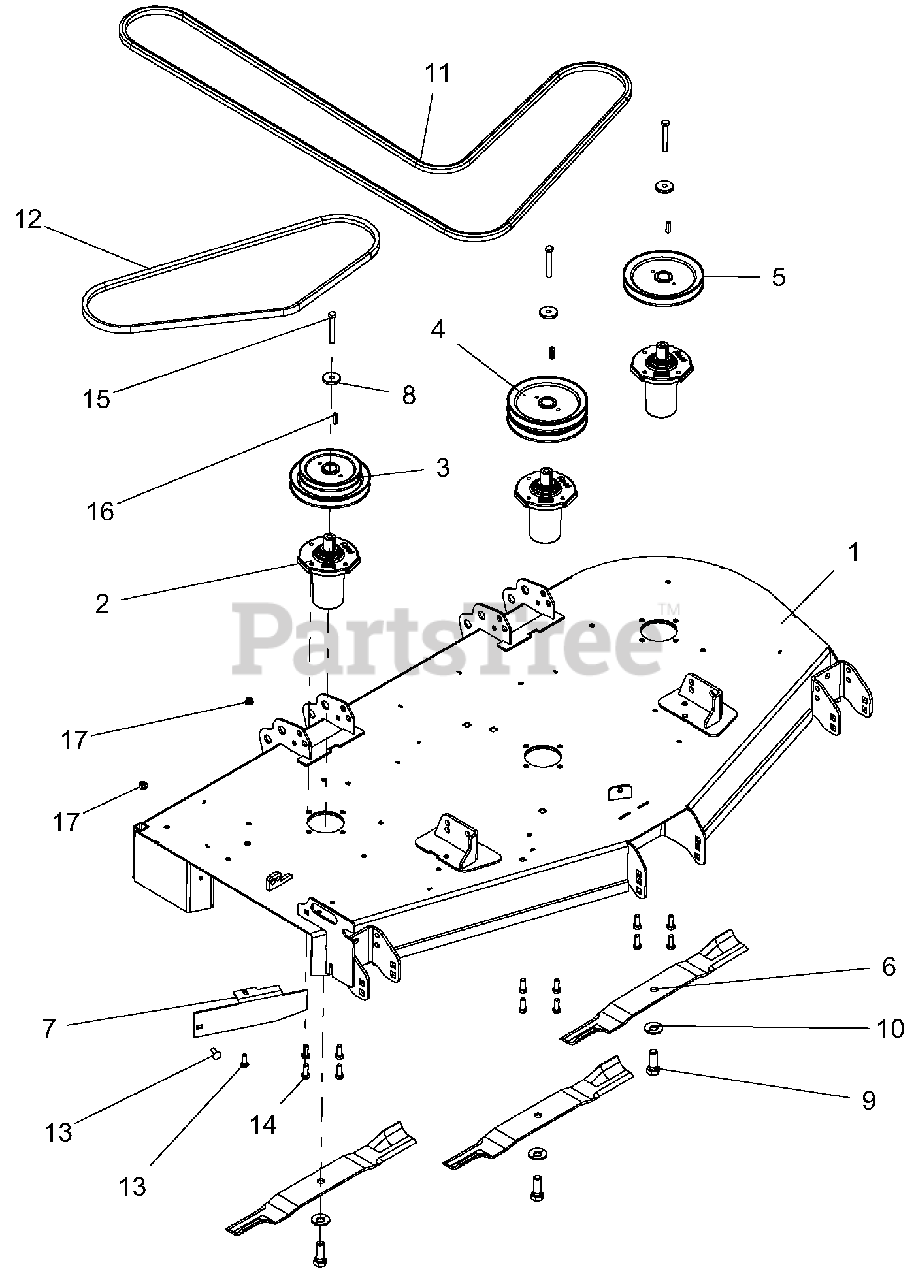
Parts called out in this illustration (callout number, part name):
1	KIT, 60" MOWER DECK W/SAFETY DECALS-RED
2	SERVICE, ASM SPINDLE- DUCTILE
3	PULLEY, DOUBLE -1" ID X 6.75" & 5.25" OD
4	PULLEY, DOUBLE 1"ID X 6.75"OD-BLACK
5	PULLEY, V-1" ID X 6.75" OD-BLACK
6	BLADE, 20.5"
7	BAFFLE, DISCHARGE, 60"-RED
8	RETAINER, SHEAVE SPINDLE
9	BLT, HEX .62-18X1.75 GR8 YWZC
10	WSHR, BLVL .63X1.625X.14
11	BELT, BB 118.00 WRAPPED HEX
12	BELT, B 63.00 RAW COGGED
13	BLT-RDHDSQSHNK .31-18X1.00YG5
14	BLT-HEX .38-16X1.00 GR5 YWZC EP30
15	BLT-HEX .38-16X2.75 GR8 YWZC
16	KEY-SQ .250X.250X1.00 RC 40-50
17	NUT-LK-NYL-FLG .31-18 YWZC
